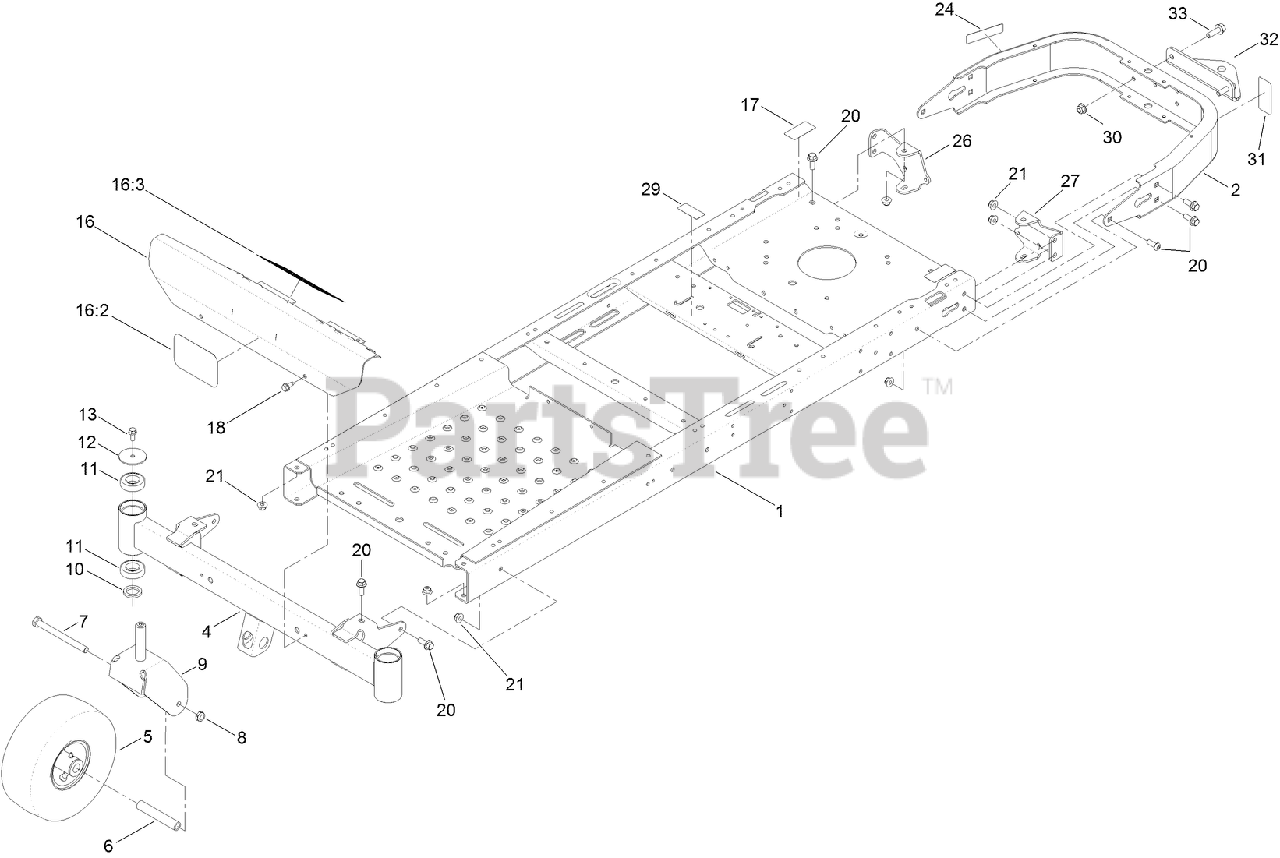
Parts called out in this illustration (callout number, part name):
2	BUMPER-REAR
4	AXLE-FRONT
5	CASTER WHEEL ASM
6	BUSHING-SPANNER
7	SCREW-HH
8	NUT-HEX
9	FORK-CASTER
10	WASHER-THRUST
11	BEARING-BALL
12	WASHER
13	SCREW-HHF
17	DECAL-BYPASS
18	SCREW-HWHTF
20	SCREW-HHF
21	NUT-HF, NI
24	DECAL-ARRESTER, SPARK
26	MOUNT-HYDRO, REAR (RH)
27	MOUNT-HYDRO, REAR (LH)
29	DECAL-LOCATION, SERVICE DEALER
30	NUT-HF, NI
32	BRACKET-HITCH
33	SCREW-HHF
